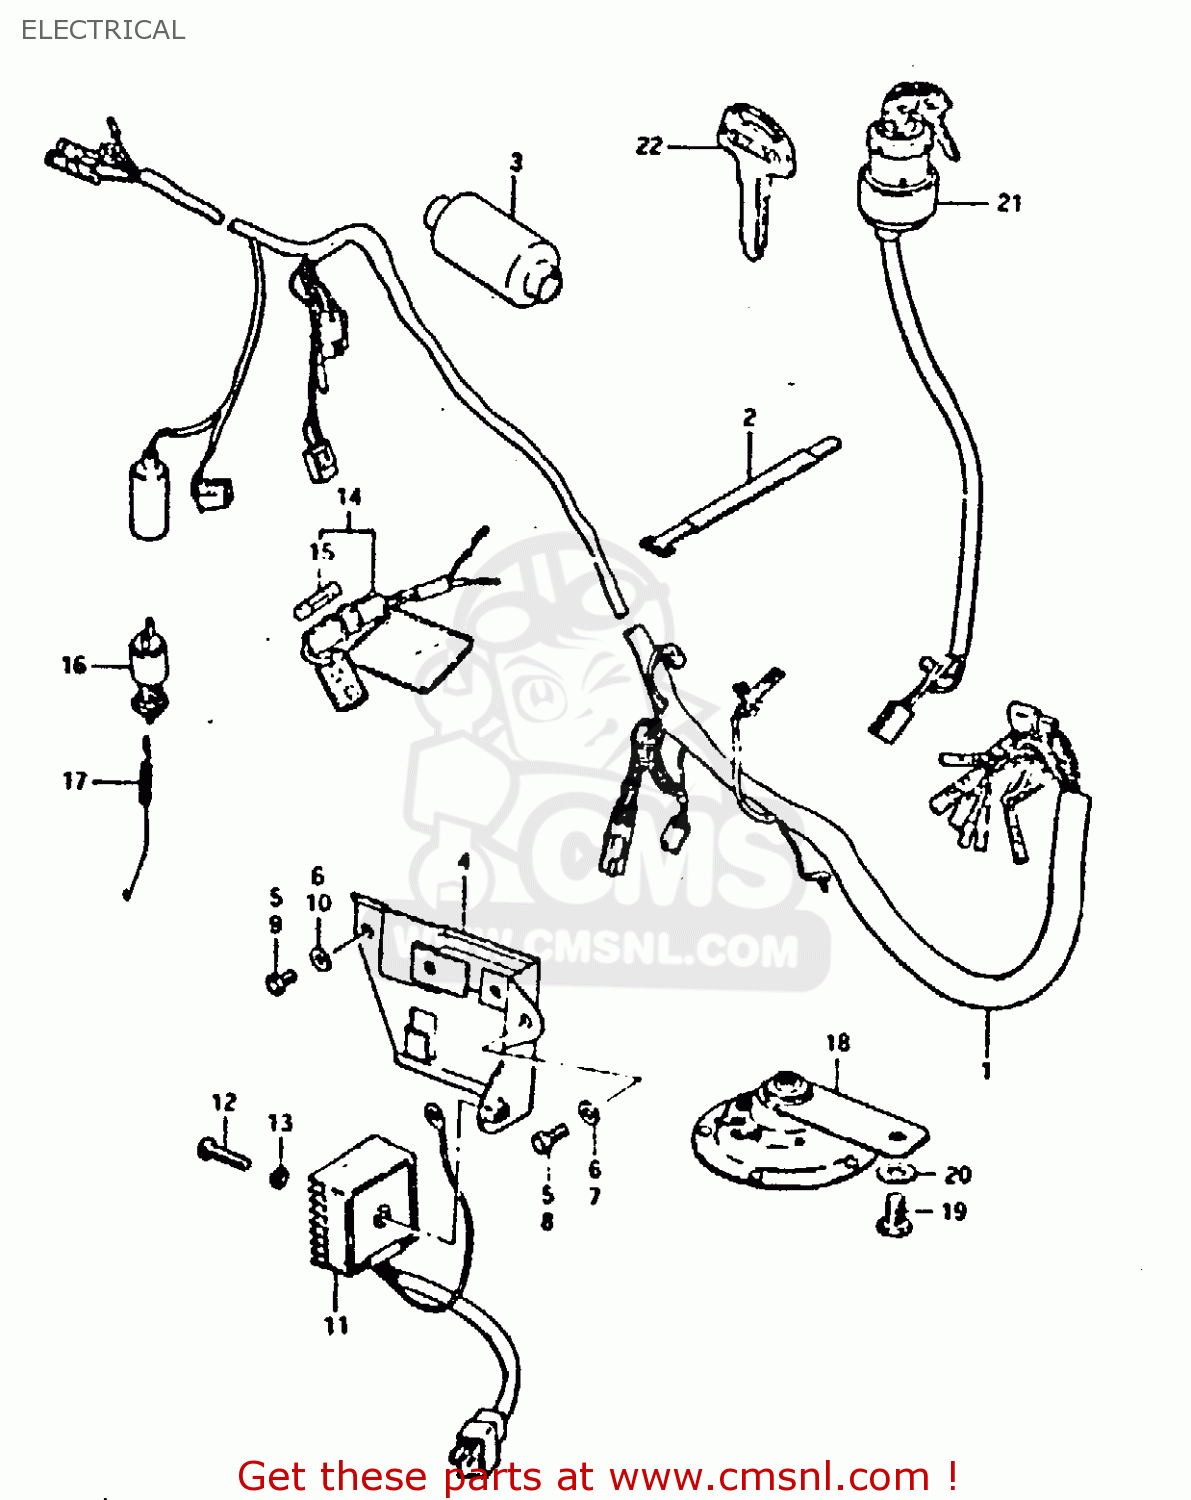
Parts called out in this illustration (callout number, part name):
1	WIRING HARNESS
2	CLAMP
3	BOOT,WIRING HARNESS
4	PLATE, ELECTRIC PARTS HOLDER
5	BOLT
6	WASHER(6,5X22X1.6)
7	WASHER
8	BOLT
9	BOLT
10	WASHER
11	RECTIFIRE ASSY, REGULATOR
12	SCREW
13	LOCK WASHER
14	BOX ASSEMBLY,FUSE
15	FUSE(15A)
16	SWITCH ASSY,BRAKE LAMP
17	SPRING
18	HORN ASSEMBLY
19	BOLT 8X12
20	WASHER
21	SWITCH ASSY, IGNITION
22	KEY,BLANK
